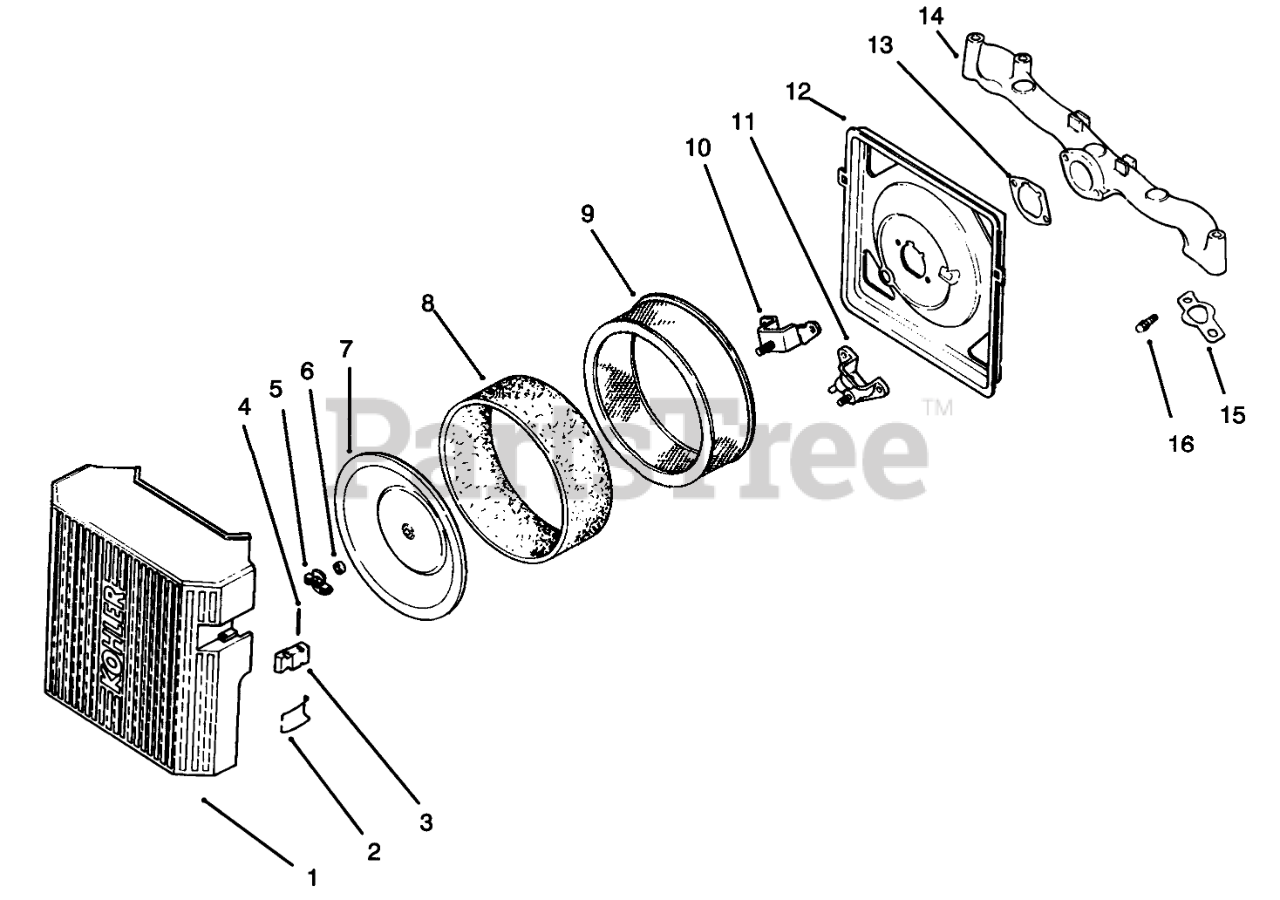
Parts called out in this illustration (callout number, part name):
1	Kit-A/C Cover INCL 2-4 (Only On: 72103;
2	Spring-Latch (Only On: 72103)
3	Latch-Lever (Only On: 72103)
4	Pin-Latch Lever (Only On: 72103)
5	Nut-Wing (Only On: 72103)
6	Seal-Air Intake (Only On: 72103)
7	Cover-Inner Air Cleaner (Only On: 72103)
8	Element-Precleaner (Only On: 72103)
9	Element-Air Cleaner (Only On: 72103)
10	Cup-Fuel Spitback (Only On: 72103)
11	Gasket-Fuel Spitback Cup (Only On: 72103)
12	Base-Air Cleaner (Only On: 72103)
13	Gasket-A/C Base (Only On: 72103)
14	Manifold-Intake (Only On: 72103)
15	Gasket-Intake Manifold (Only On: 72103)
16	Screw M6x1.0x18 (Only On: 72103)
